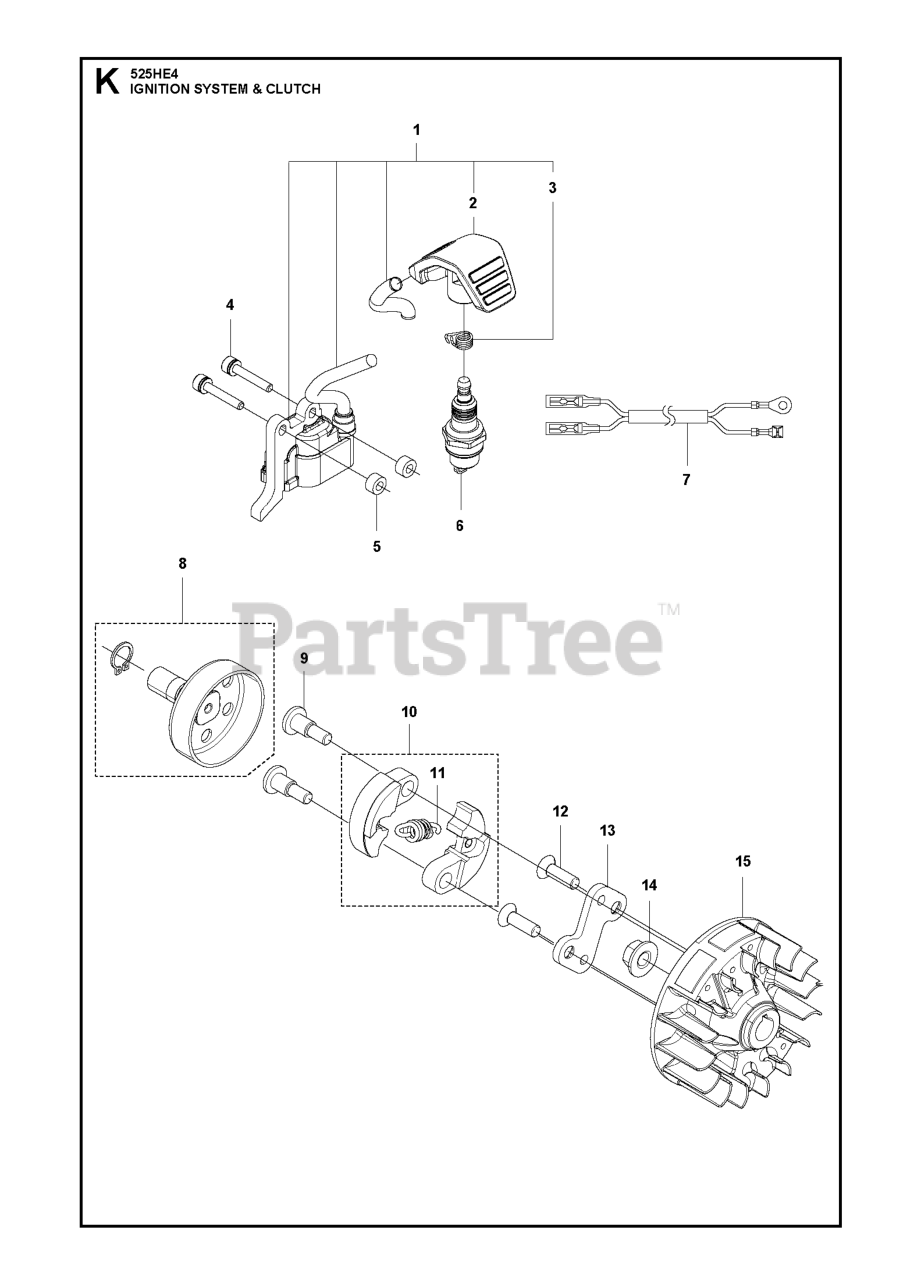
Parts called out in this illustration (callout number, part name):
1	IGNITION COIL ASSY
2	SPARK PLUG CAP
4	BOLT M4 X 25
6	SPARK PLUG HQT-2 RESISTOR
7	SHORT CIRCUIT CABLE
8	KIT CLUTCH DRUM ASSY
9	SCREW CLUTCH
11	CLUTCH SPRING
13	CLUTCH HUB
14	NUT
